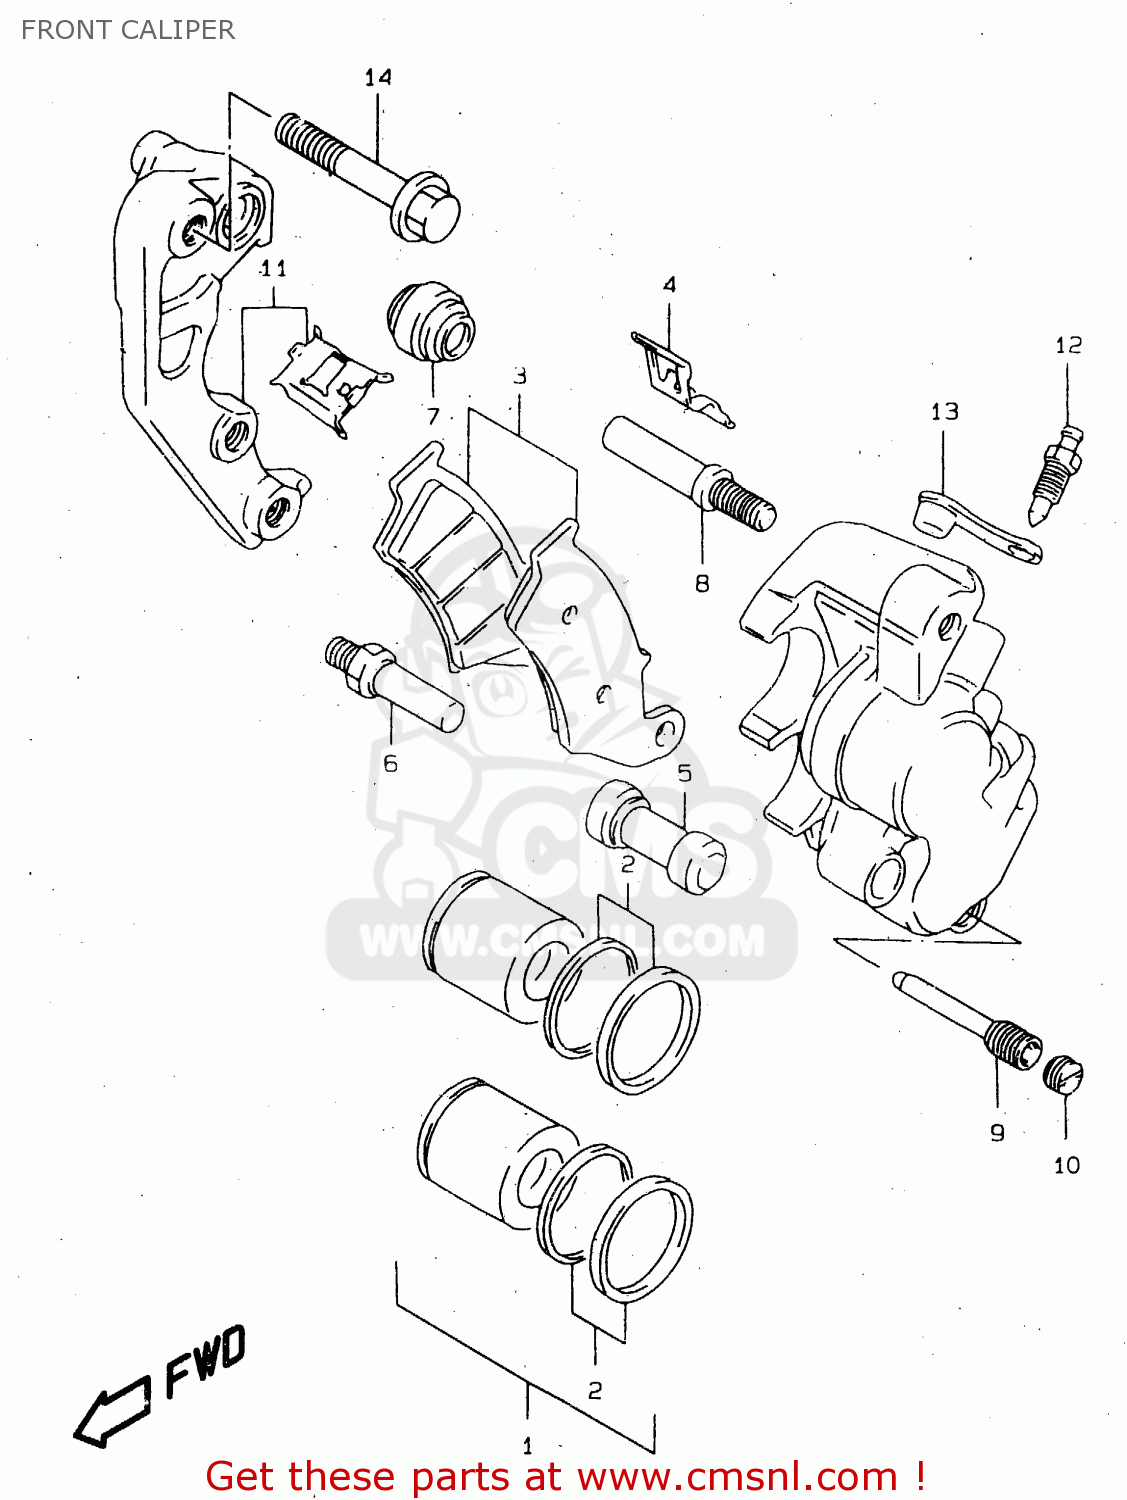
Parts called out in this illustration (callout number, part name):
1	PISTON SET
2	SEAL SET,PISTON
3	PAD SET (NAS)
4	SPRING,PAD
5	BOOT
6	BOLT
7	BOOT
8	PIN
9	PIN,HANGER
10	PLUG,PIN
11	BRACKET
12	BLEEDER
13	CAP,BLEEDER
14	BOLT(8X40)
